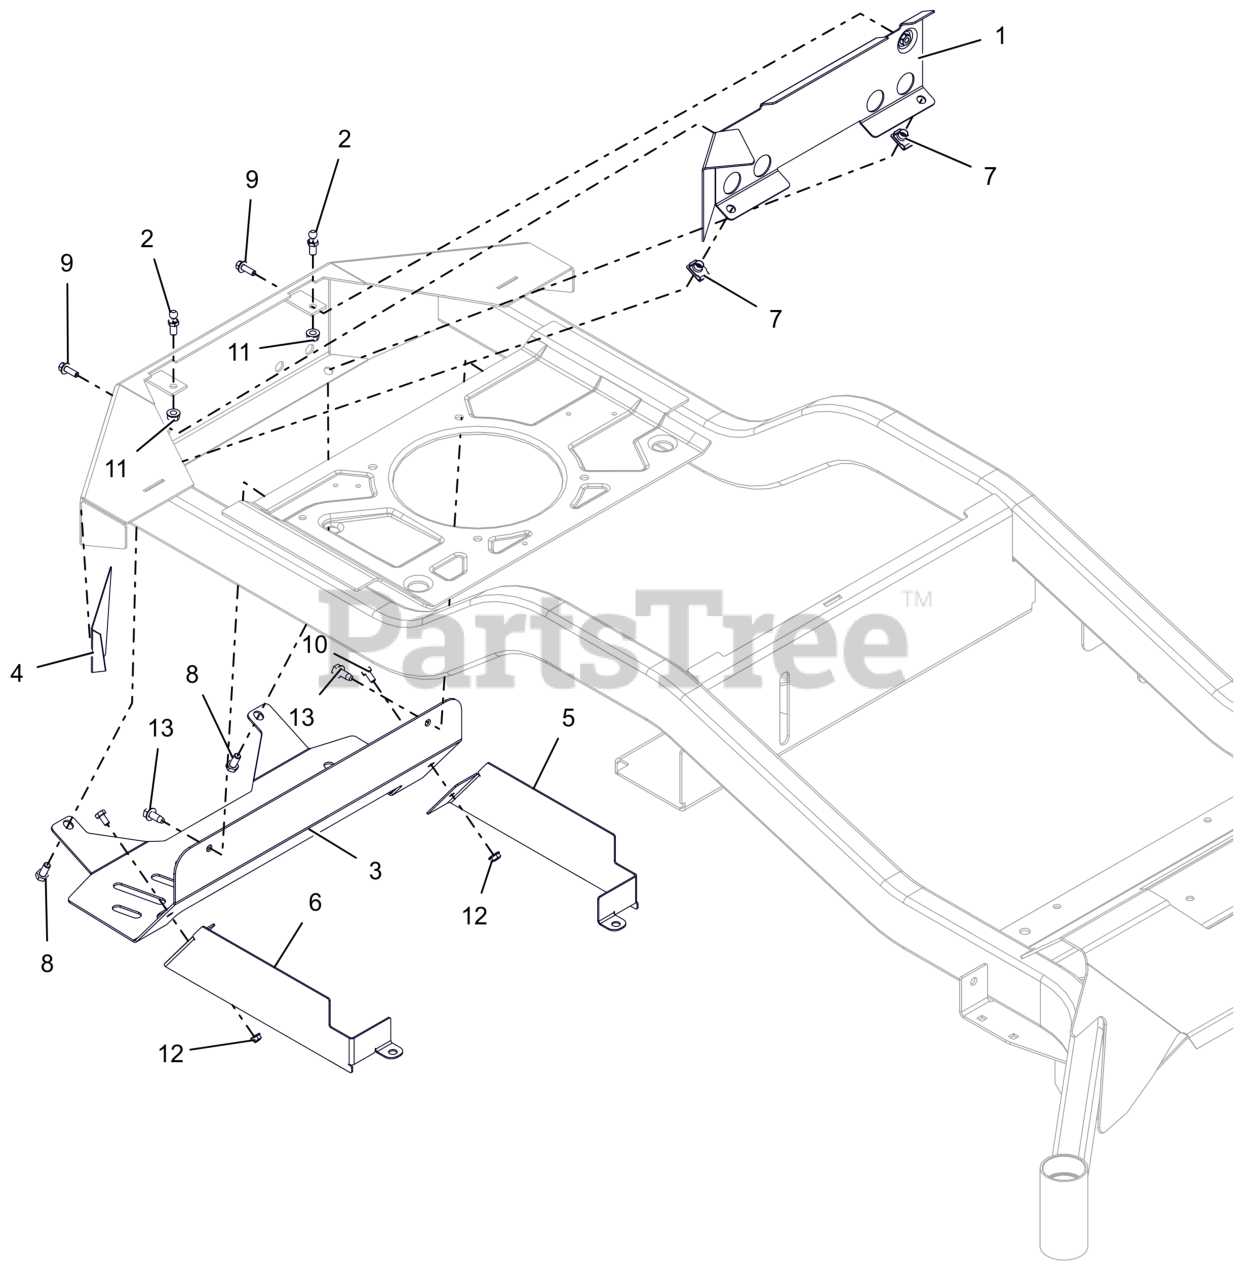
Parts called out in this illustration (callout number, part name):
1	WMT, HEAT BAFFLE
2	STUD- BALL
3	SHIELD, HEAT (HD)
4	TAPE, HEAT DEFLECTOR
5	GUARD,REAR CLUTCH LH
6	GUARD,REAR CLUTCH RH
7	NUT-CLIP RETAINER 5/16-18X.56
8	BLT,HEX .31-18X.75 G5 ZCC
9	BLT,HEX-FLG .25-20X.75 G5 BFP
10	BLT,HEX .25-20X.50 G5 ZCC
11	NUT,LK-CTR-FLG .31-18 GF ZCC
12	NUT-LK-TOP-FLG .250-20 GF ZCC
13	SCR,TAP .312-18X.75 HWH TR ZCC
